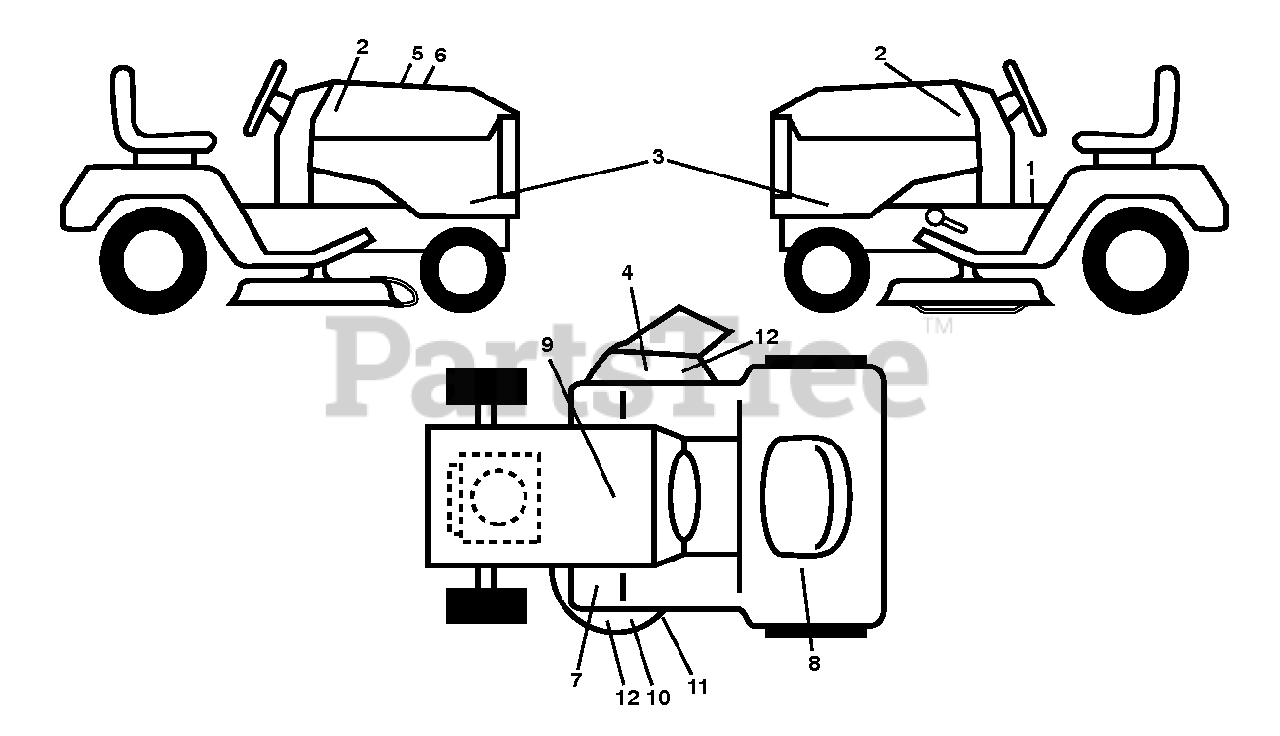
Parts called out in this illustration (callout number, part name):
1	DECAL.FENDER.WARNING.ENGLISH
2	DECAL.BADGE.170MM.TEXTLOGO.
3	DECAL.SDPL.HUSQGT2.YT.48XLS
4	DECAL.DECK.6MIL./DEF.SHLD.WARN
5	DECAL.WARNING.CUST.RESP.E85.
6	DCL.RPL.KAW.FR730.TLB.48F.K46
7	DECAL.PEDAL.HUSQ.CROWN
8	DECAL.WARN.FUEL.RESERVE
9	DECAL BTRY SYMBOLS
10	DECAL.HV.REINFORCED.DECKS.2012
11	DECAL.MOWER.SCH.48/54.PREM
12	DECAL.DECK.6MIL.EURO.NOSTEP
